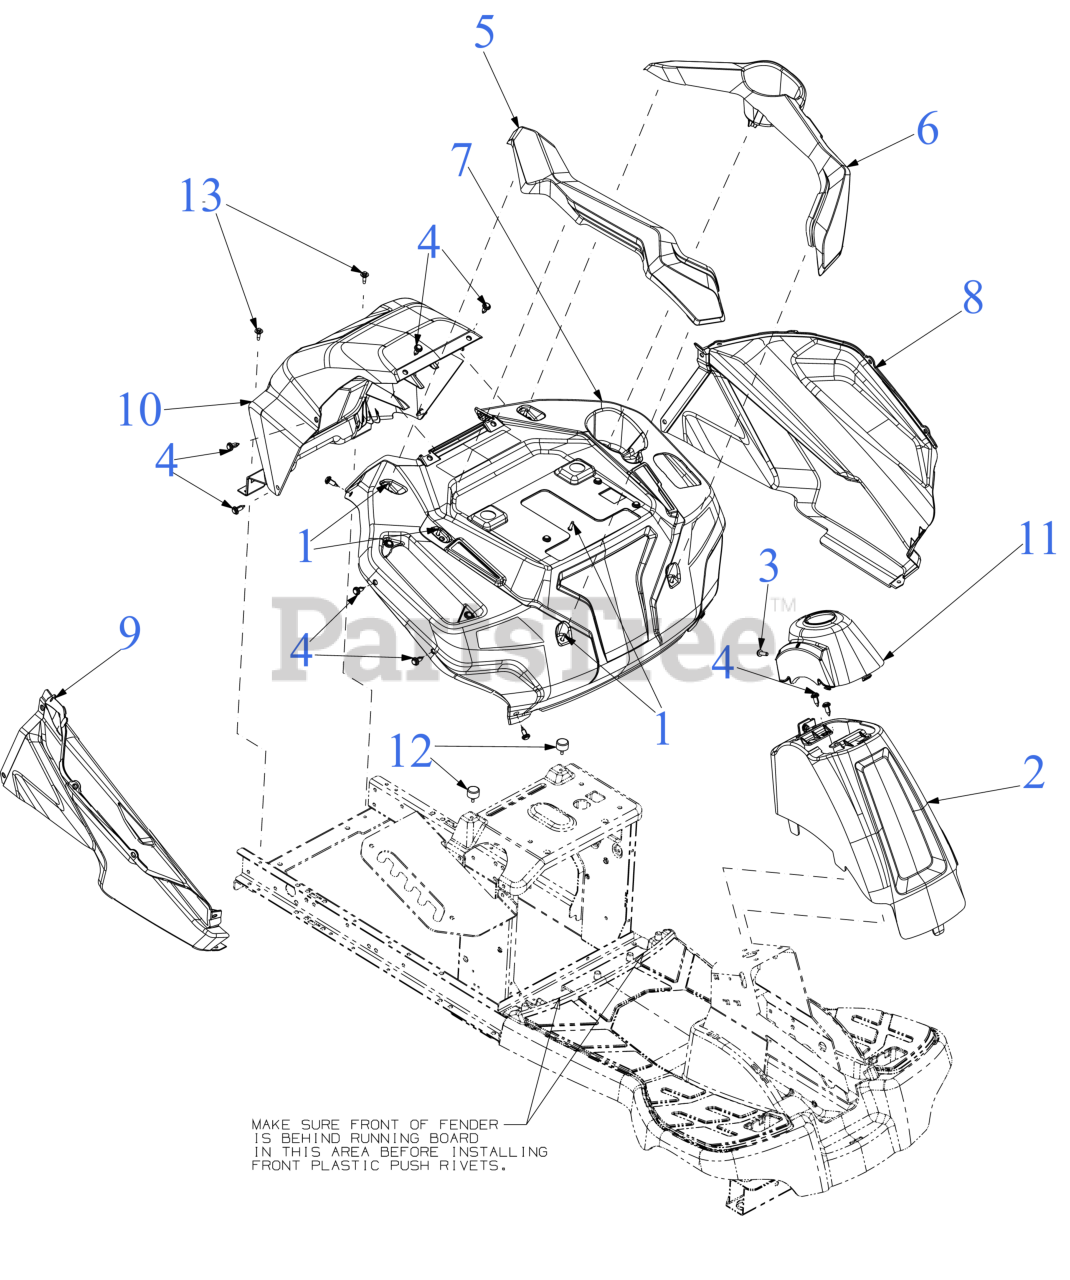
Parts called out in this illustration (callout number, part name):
1	SCREW, #8-16X.750 PH
2	COLUMN COVER (BLACK)
3	SCREW 1/4-20X.75
4	PLASTIC RIVET
5	FENDER TRIM (RH)
6	FENDER TRIM (LH) (NO USB)
8	BODY PANEL (LH)
9	BODY PANEL (RH)
11	STEERING COLUMN CAP
12	BUMPER .62 DIA x .50
13	SHOULDER SCREW M6-1 .368 X.115
